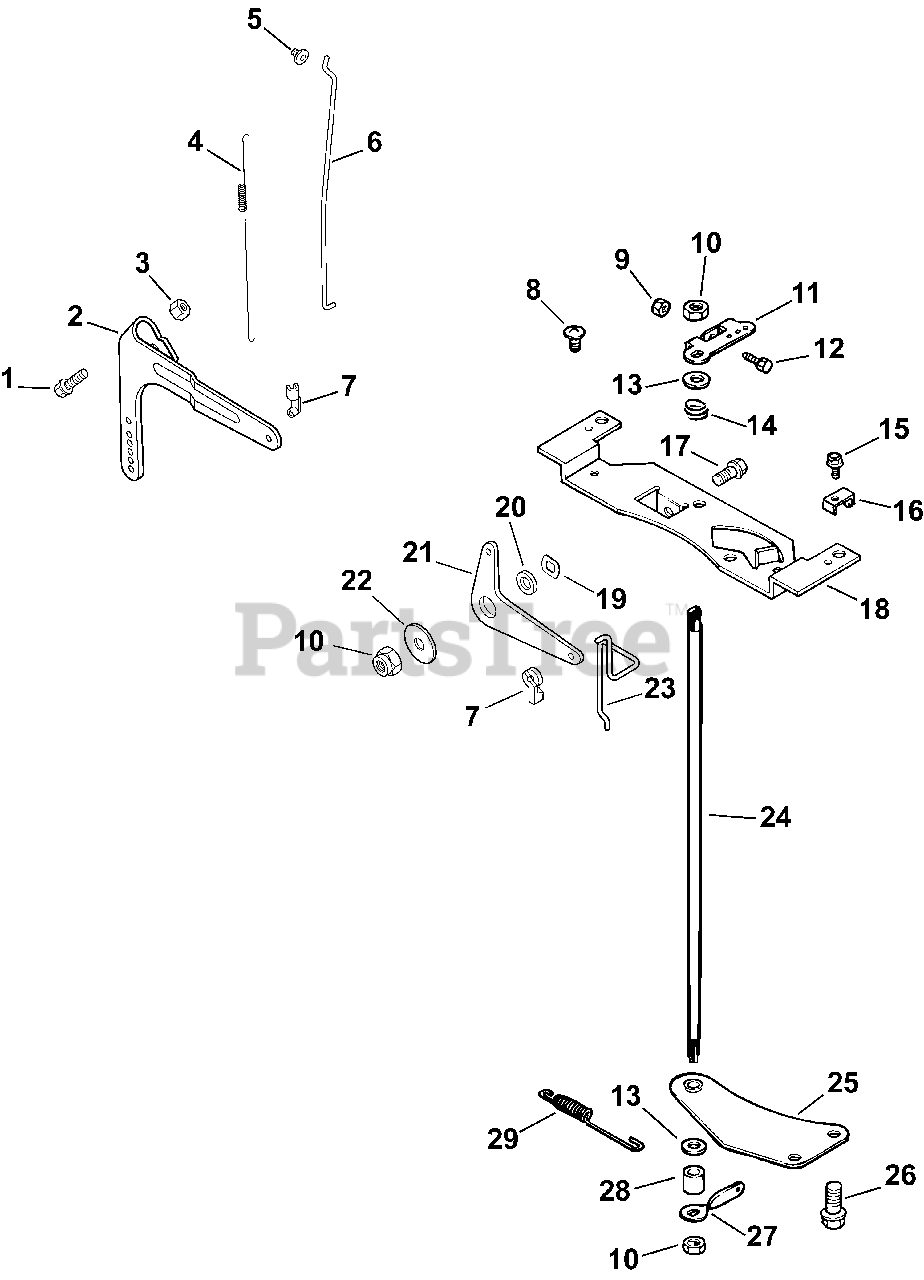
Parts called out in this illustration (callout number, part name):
1	BOLT, RD HD SQ NECK M6X1.0X25
2	LEVER, GOVERNOR-USE 24 090 57-S
3	NUT, FLG M6X1.0
4	SPRING, LINKAGE
5	BUSHING, LINKAGE RETAINING
6	LINKAGE, THROTTLE
7	BUSHING, THROTTLE LINKAGE
8	SCREW, PHL HD 11-16X3/4"
9	NUT, M4X0.7
10	NUT, LOCK M6X1.0
11	LEVER, THROTTLE CONTROL
12	SCREW, CAP M4X.7X30
13	WASHER, FLAT 1/4"
14	SPRING, THROTTLE SHAFT
15	SCREW,FLG THD FRM M5X0.8X16-(#25086398S)
16	CLAMP, CABLE
17	SCREW, FLG M6X1.0X16
18	BRACKET, CONTROL-USE 24 126 219-S
19	WASHER, SPRING 3/8"
21	LEVER, CHOKE
22	WASHER, FLAT 1/4"
23	LINKAGE, CHOKE
24	SHAFT, THROTTLE
25	BRACKET, THROTTLE SHAFT-USE 24 126 162-S
26	SCREW,FLG THD FRM M6X1.0X16-(#25086397S)
27	LEVER, THROTTLE CONTROL
29	SPRING, GOVERNOR (GREEN)
